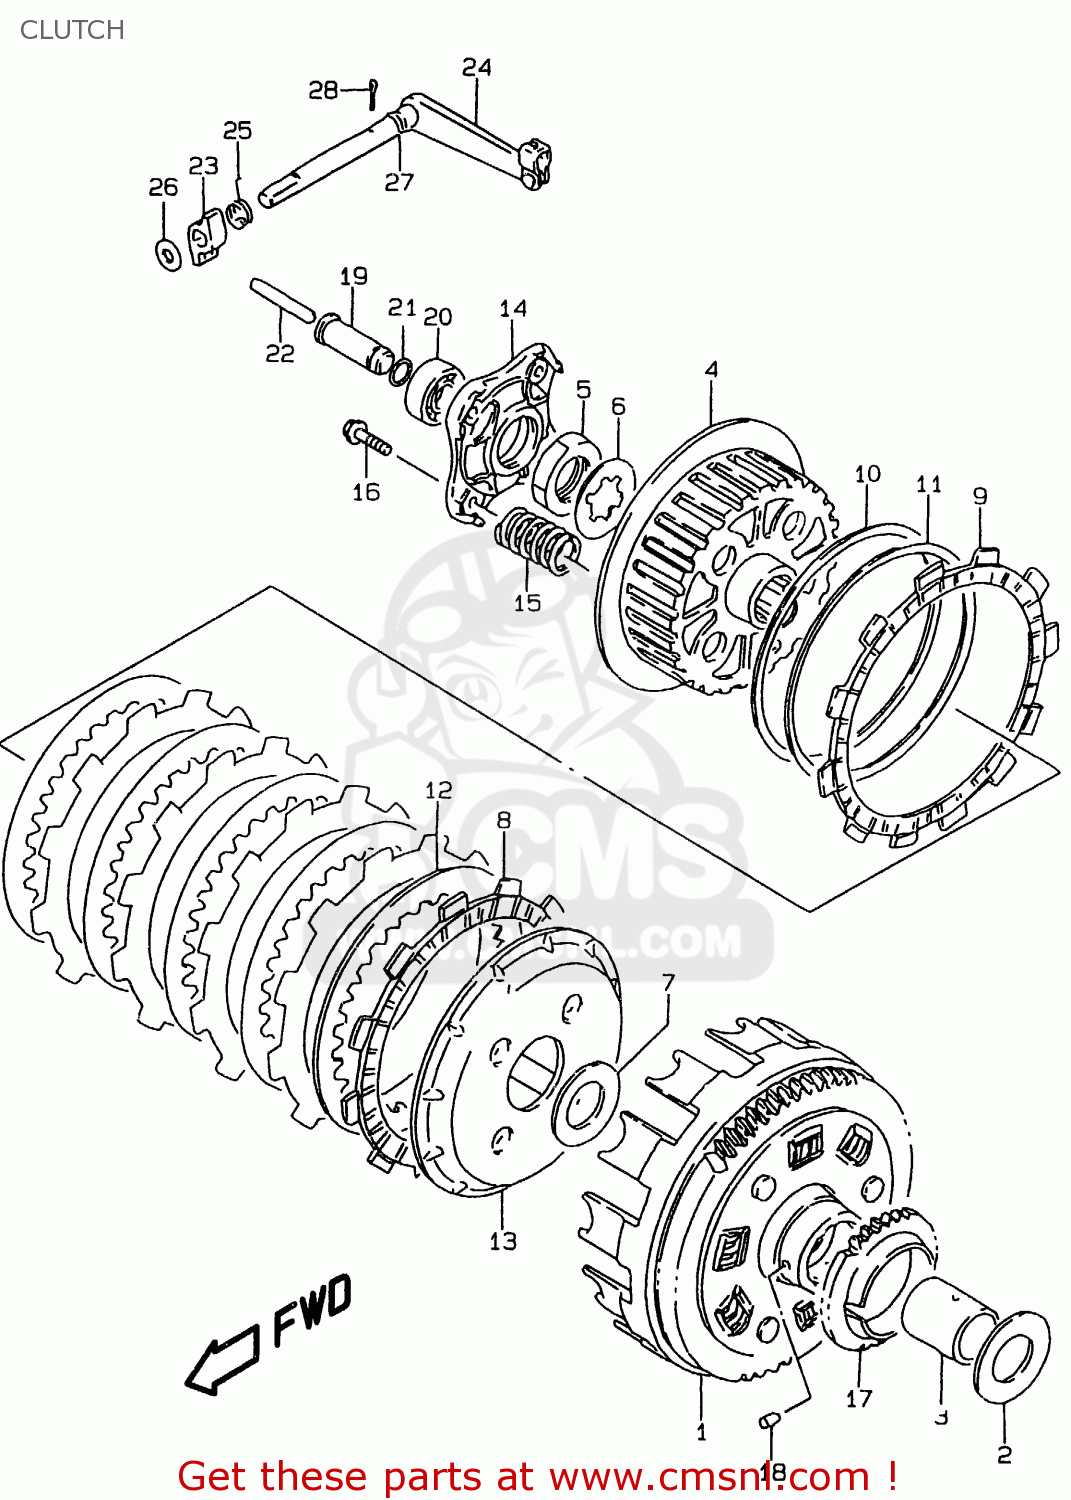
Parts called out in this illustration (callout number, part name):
1	GEAR ASSY,PRI DRIVEN
2	WASHER
3	SPACER(22X28X32.5)
4	HUB,CLUTCH SLEEVE
5	NUT
6	WASHER,LOCK
7	WASHER
8	PLATE,CLUTCH DRIVE (NAS)
9	PLATE,CLUTCH DRIVE(T:3.5) (NAS)
10	SEAT,WAVE WASHER(T:1.4)
11	WASHER
12	PLATE,CLUTCH DRIVEN(T:1.6) (NAS)
13	DISC,CLUTCH PRESSURE
14	PLATE,RELEASE
15	SPRING
16	BOLT
17	GEAR,ENG OIL PUMP DRIVE
18	PIN(6X6)
19	PIECE,CLUTCH PUSH
20	BEARING(12X28X8)
21	O RING(D:1.9,ID:8.6)
22	ROD,CLUTCH PUSH
23	CAM,CLUTCH RELEASE
24	ARM ASSY,CLUTCH RELEASE
25	SPRING
26	WASHER,THRUST
27	O RING(D:1.9,ID:6.8)
28	PIN 20X20
